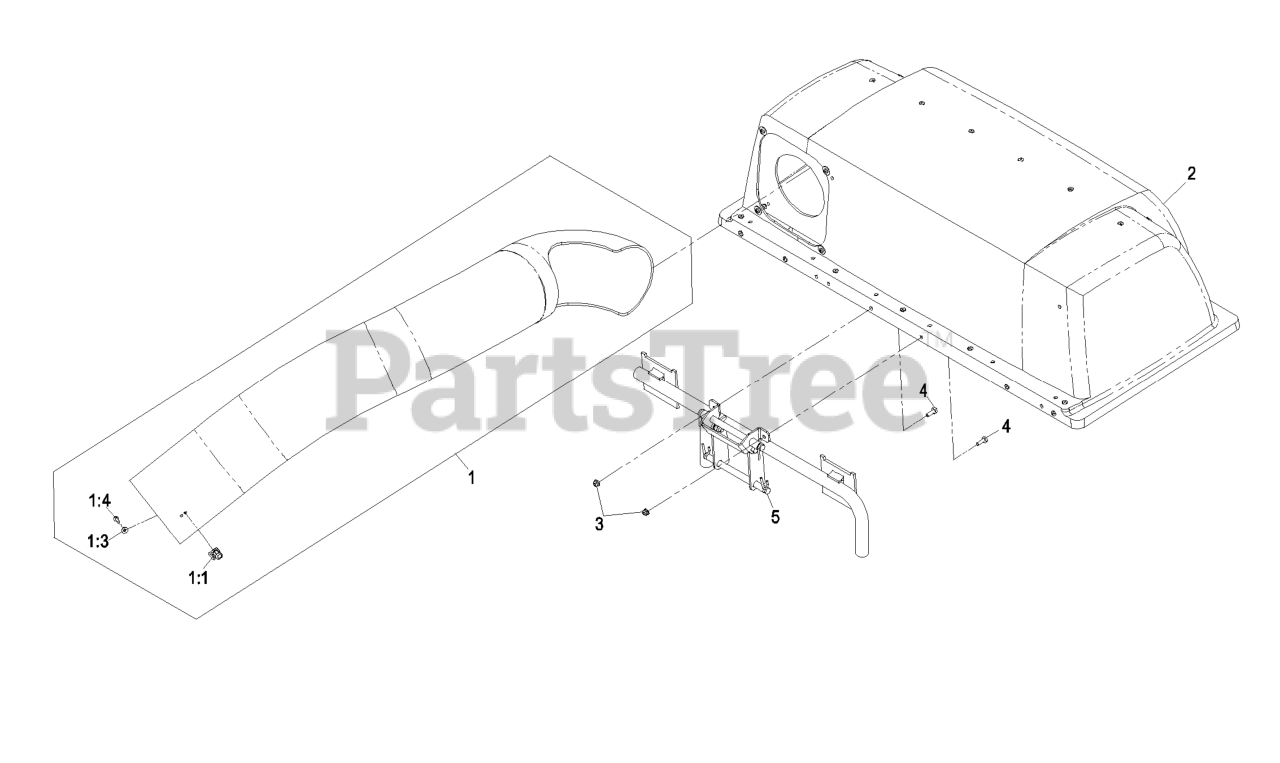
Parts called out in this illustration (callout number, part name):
1	UPPER TUBE ASM
1:1	LATCH-KEEPER
1:3	WASHER-FLAT
1:4	SCREW-PPH
4	SCREW-HH
5	BAGGER MOUNT ASM
